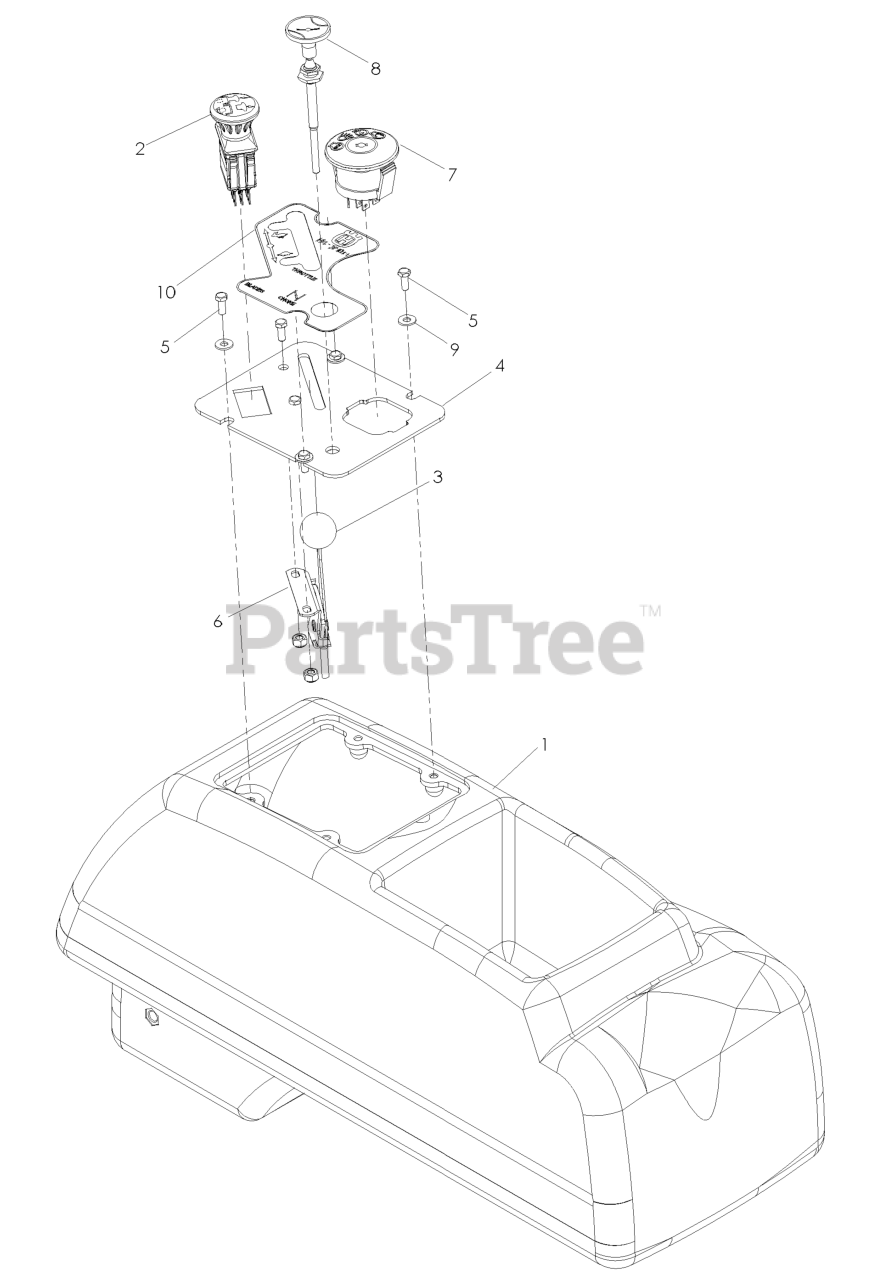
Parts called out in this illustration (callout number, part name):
1	FENDER CONSOLE
2	SWITCH, PTO 10 AMP
3	THROTTLE CABLE
4	CONSOLE PLATE, BLACK
5	HCS #10-24 X 1/2
6	NUT 10-24 NYLOC
7	RP IGNITION SWITCH
8	CHOKE CONTROL
9	WASHER #10
10	3/8-16 X 1-1/4 FHSCS GR5 BLK
